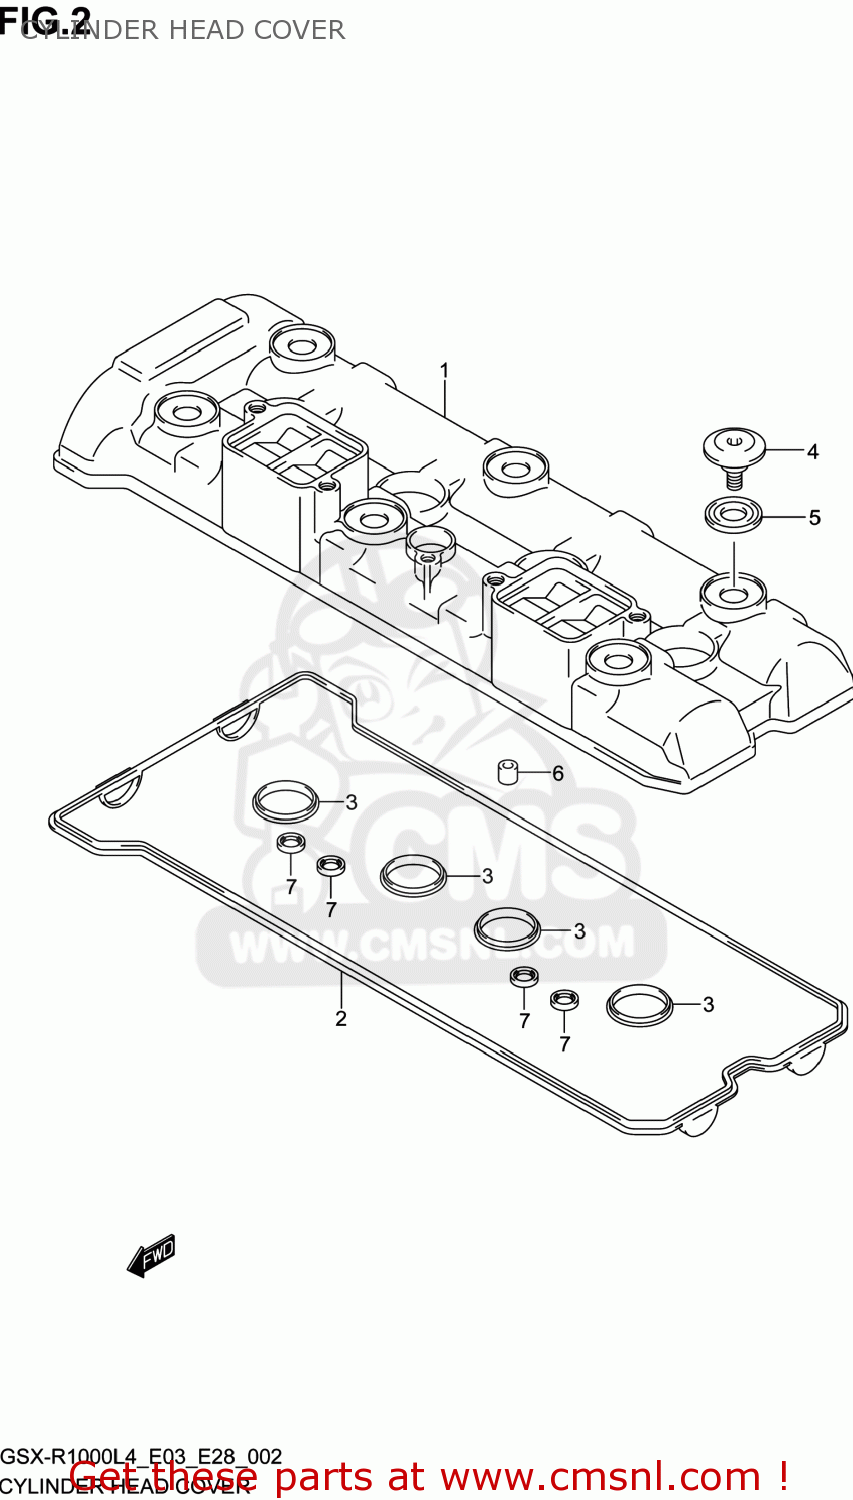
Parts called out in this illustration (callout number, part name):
1	COVER,CYLINDER HEAD
2	GASKET,CYL HEAD COVER NO.1 (NAS)
3	GASKET,CYL HEAD COVER NO.2
4	BOLT(7X17.5)
5	WASHER,CYL HEAD COVER
6	PIN(8.2X10X13)
7	GASKET,2ND AIR PASSAGE (NAS)
